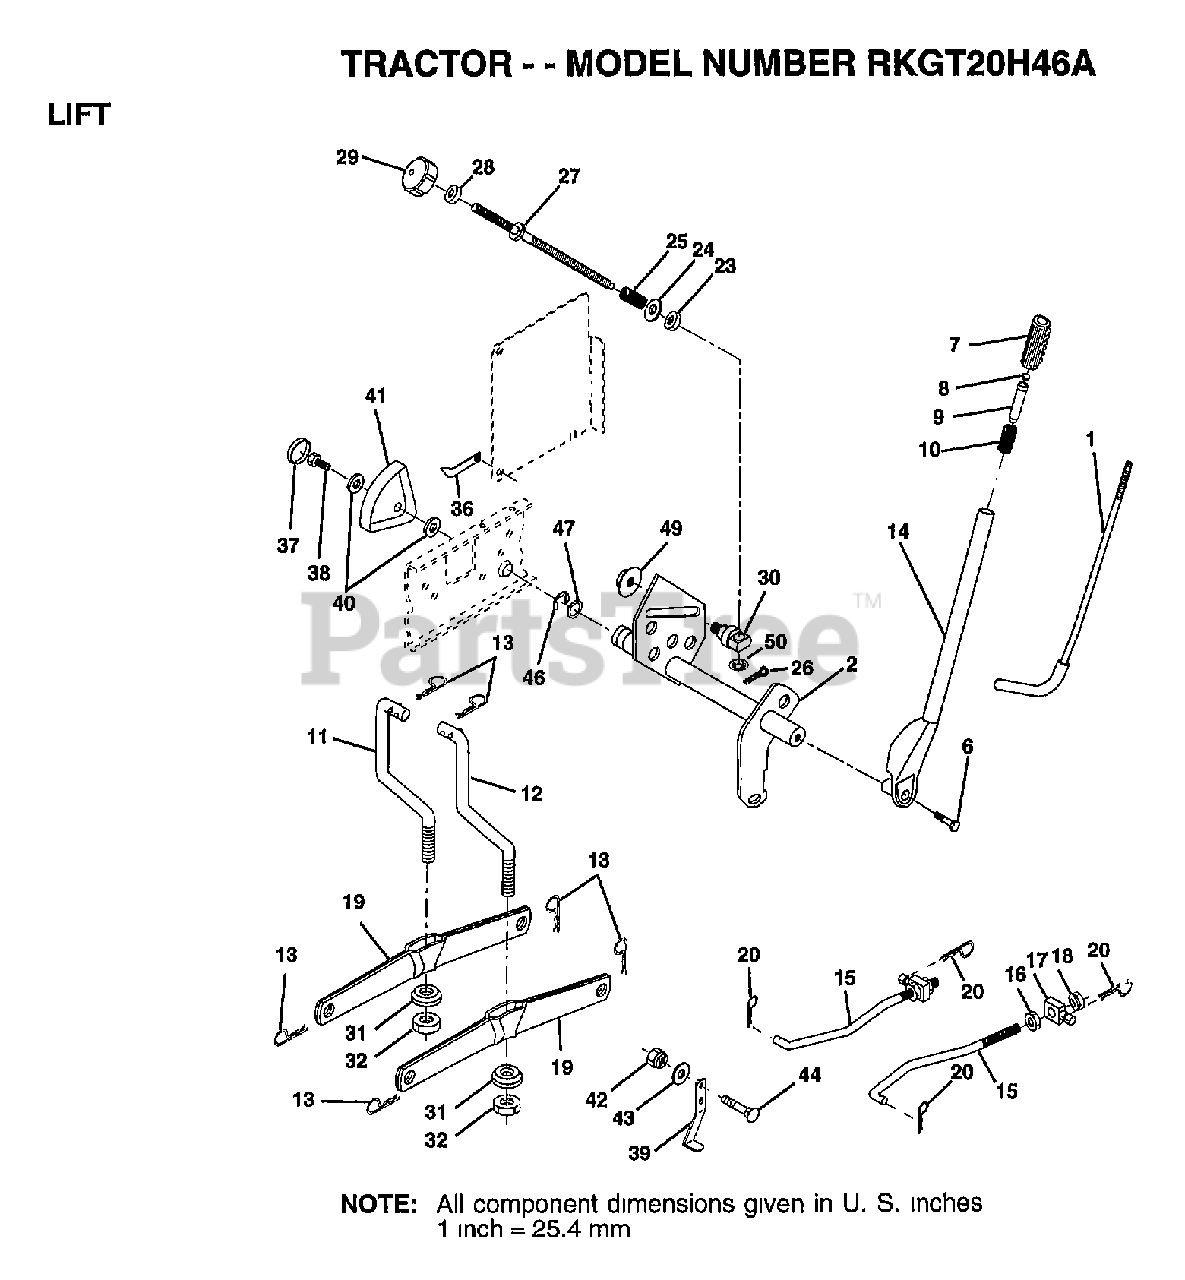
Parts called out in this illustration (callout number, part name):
1	LEVER ROD LT
2	LEVER ASSY LIFT.RH.
3	PIN-GROOVE LT
5	WASHER
6	"BOLT,HEX"
7	GRIP HANDLE
10	SPRING T
11	LINK.LIFT.LH.GTV
12	LINK.LIFT.RH.GTV.
14	LEVER.ASM.LIFT.RH
15	LINK.FRONT
16	NUT
17	TRUNION
18	NUT LTV
19	ARM SUSP REAR
20	RETAINER SPRING
23	NUT T
24	WASHER
25	SPRING.COMP.INF.H
27	ROD.ADJ.LIFT
28	NUT
29	KNOB INF 3/8-16
30	TRUNNION
31	BEARING PVT LH
32	NUT.CROWNLOCK.3/8
36	POINTER-INDICAT
37	"PLUG,HOLE"
38	SCREW
39	STOP.OVER.CENTER
40	WASHER
41	HEIGHT INDICATOR
43	WASHER GT
44	BOLT
46	E-RING
47	WASHER
49	NUT.HXFLG.LOCK.
50	NUT PUSH M
